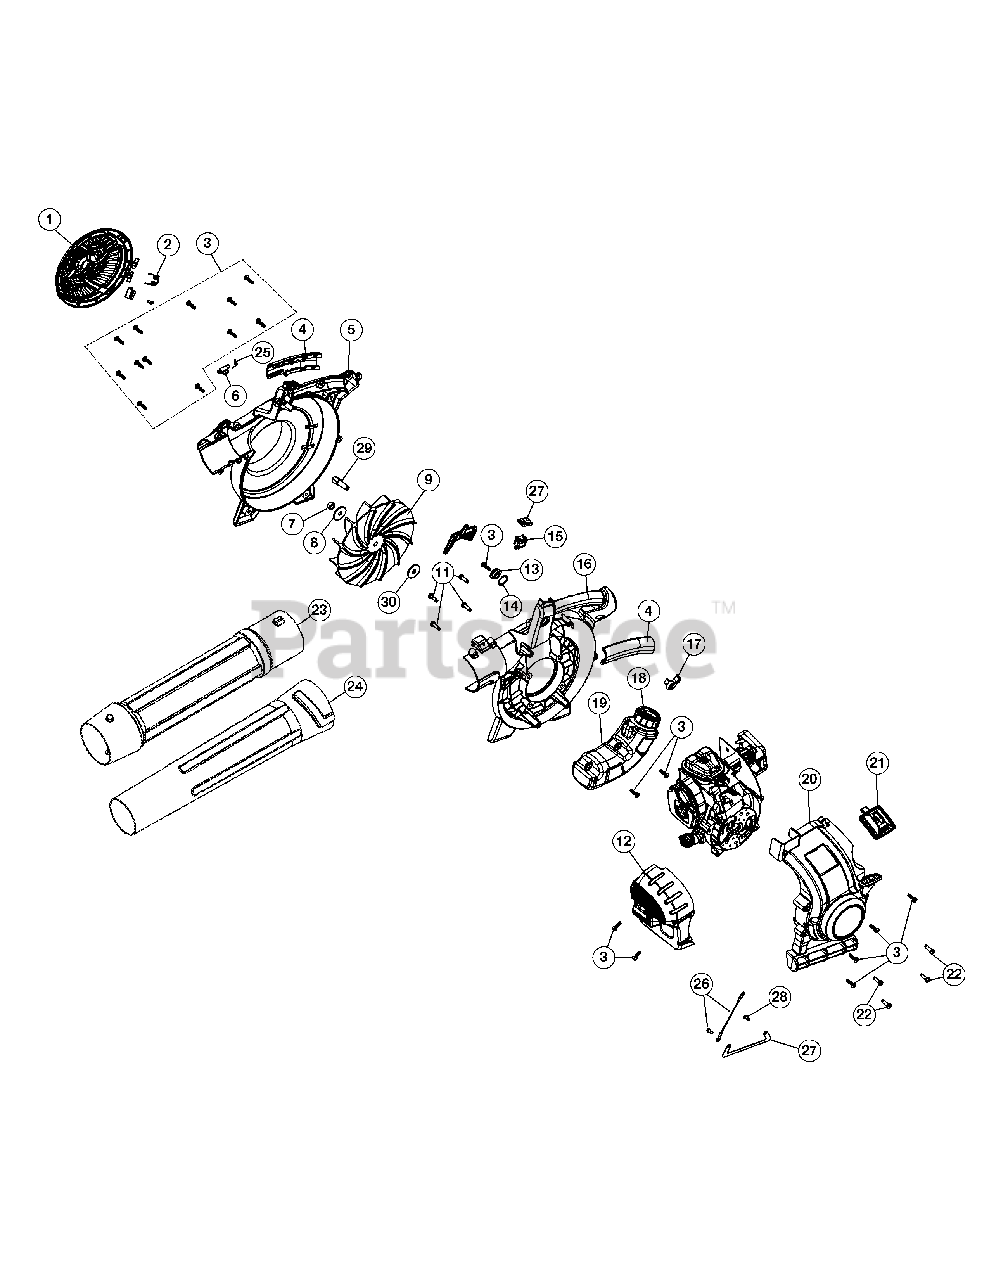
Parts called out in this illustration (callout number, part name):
1	Intake Cover Assembly
4	Handle Grips
5	Impeller Housing (Incl. 4)
6	Latch Tube
10	Throttle Trigger
11	Screw
12	Muffler Cover (Incl. 3)
13	Inner Trigger Lock
14	Wavey Washer
16	Impeller Housing (Incl. 4)
17	Outer Trigger Lock
19	Fuel Tank Assembly (Incl. 18)
20	Engine Cover Assembly (Incl. 3, 21 & 22)
21	Spark Plug Cover
23	Upper Tube
24	Lower Tube
25	Latch Spring
26	Wire Ground
27	Strap Ground
28	Screw
